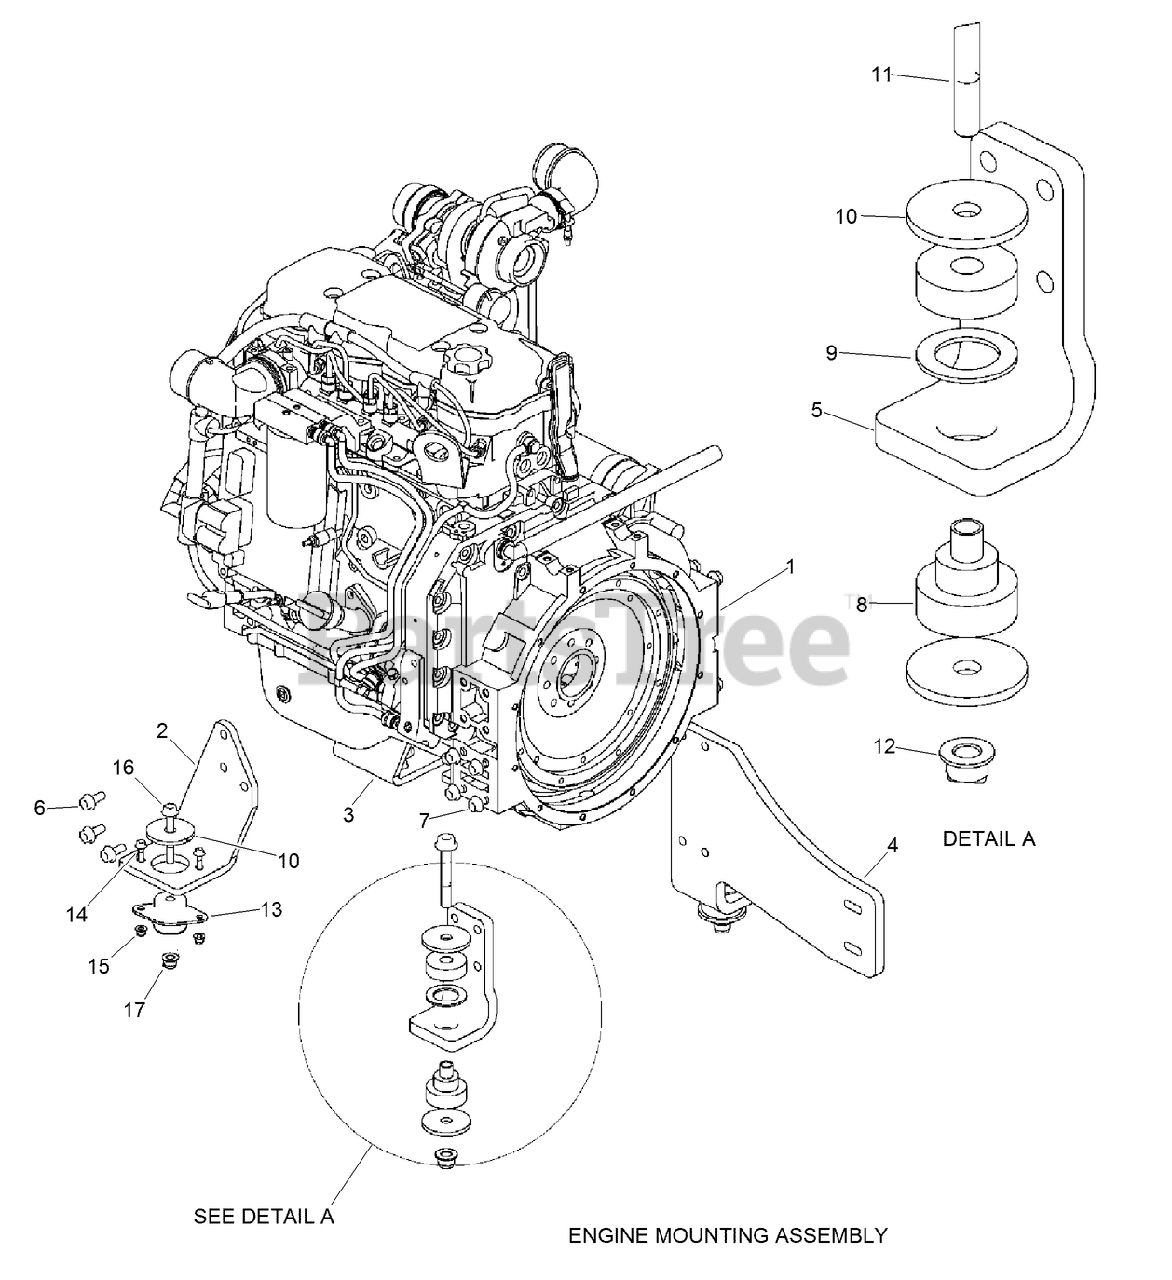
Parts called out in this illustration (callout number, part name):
1	ENGINE - Cummins 148 HP
2	MOUNT - Engine (Front Left)
3	MOUNT - Engine (Front Right)
4	MOUNT - Engine (Rear Right)
5	MOUNT - Engine (Rear Left)
6	SCREW, METRIC FLANGE w/BODY-M12 x 30
7	SCREW-HHF
8	ISOLATOR-MOUNT, UNIVERSAL
9	SPACER-ISOLATOR
10	WASHER
11	SCREW-FLANGE
12	NUT-HHF
13	ISOLATOR MOUNT - Front
14	SCREW, METRIC FLANGE FULL - M8 x 25
15	NUT-TORQUE, PREVAILING
16	SCREW, METRIC FLANGE w/BODY-M12 x 90
17	NUT-HHF, LOCK
